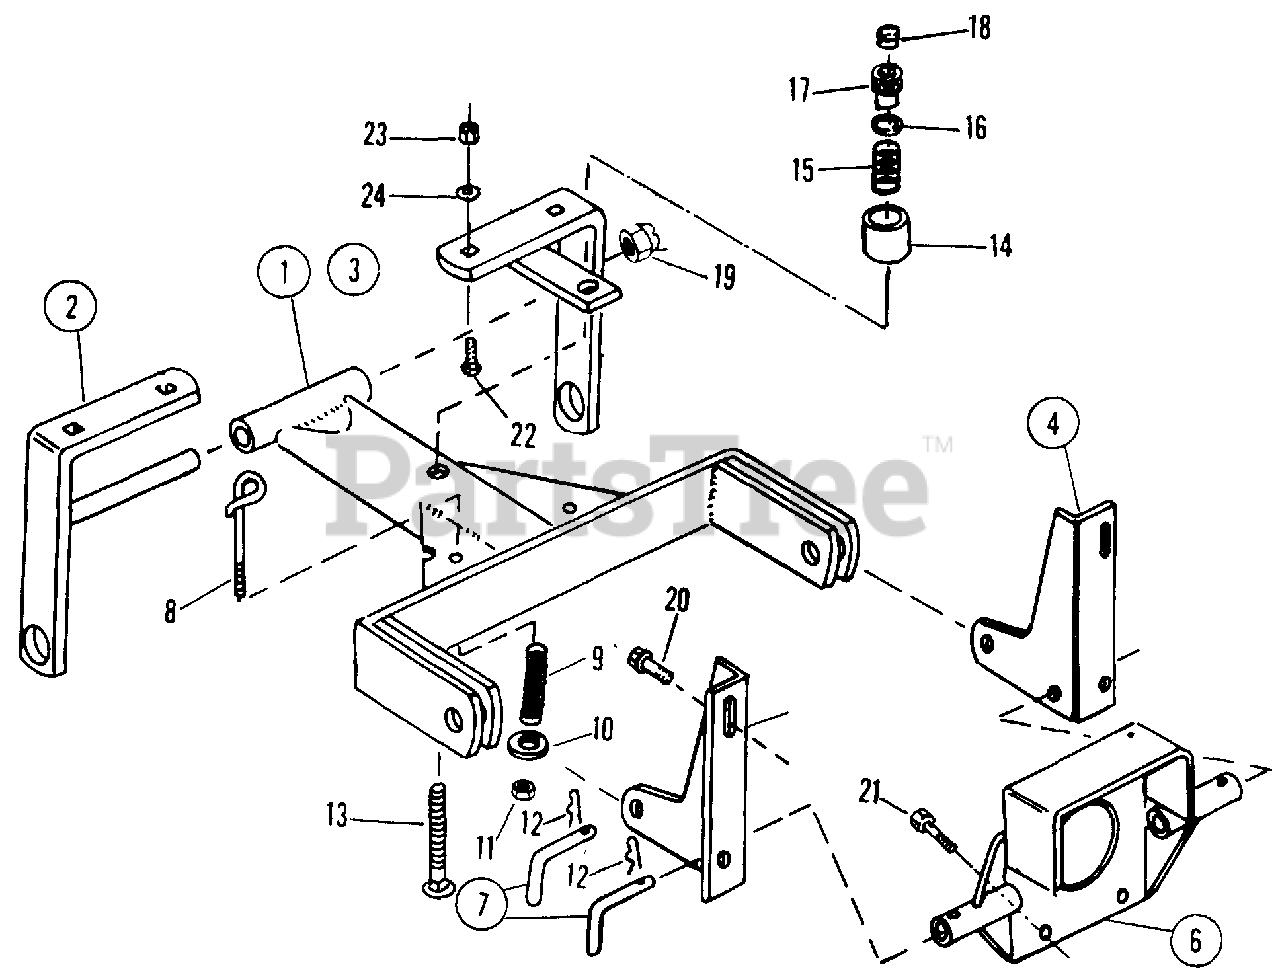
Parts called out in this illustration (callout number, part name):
1	LINK, UPPER HITCH
2	BRACKET, RIGHT HAND
3	BRACKET, LEFT HAND
4	BRACKET, HITCH MOUNT - RIGHT HAND
5	BRACKET, HITCH MOUNT - LEFT HAND
6	MOUNT, GEAR BOX
7	L-PIN, SHORT
8	ROD, LOCK
9	SPRING, LOCK ROD .406" ID x 3.75" Long
10	WASHER, SPECIAL
11	LOCKNUT, 1/4 HEX
12	PIN, 1/8 x 1-7/8 COTTER
13	BOLT, SPECIAL CARRIAGE
14	TUBE, TENSION LIMIT
15	SPRING, BELT TENSION .437" ID x 1.25" Long
16	WASHER, SPECIAL WIDE RIM
17	KNOB, BELT TENSION TORQUE 3/8-16 x 2.37" OD
18	GROMMET .312" ID for .562" Hole (Atlantic India Rubber #2856)
19	LOCKNUT, 5/8 HEX
20	BOLT, HEX FLANGE 3/8 x 1
21	BOLT, 3/8-16 x 1-1/4 HEX
22	BOLT, 1/2C x 1-1/4 CARRIAGE
23	NUT, 1/2-13 HEX LOCK
24	WASHER, 1/2 PLAIN
